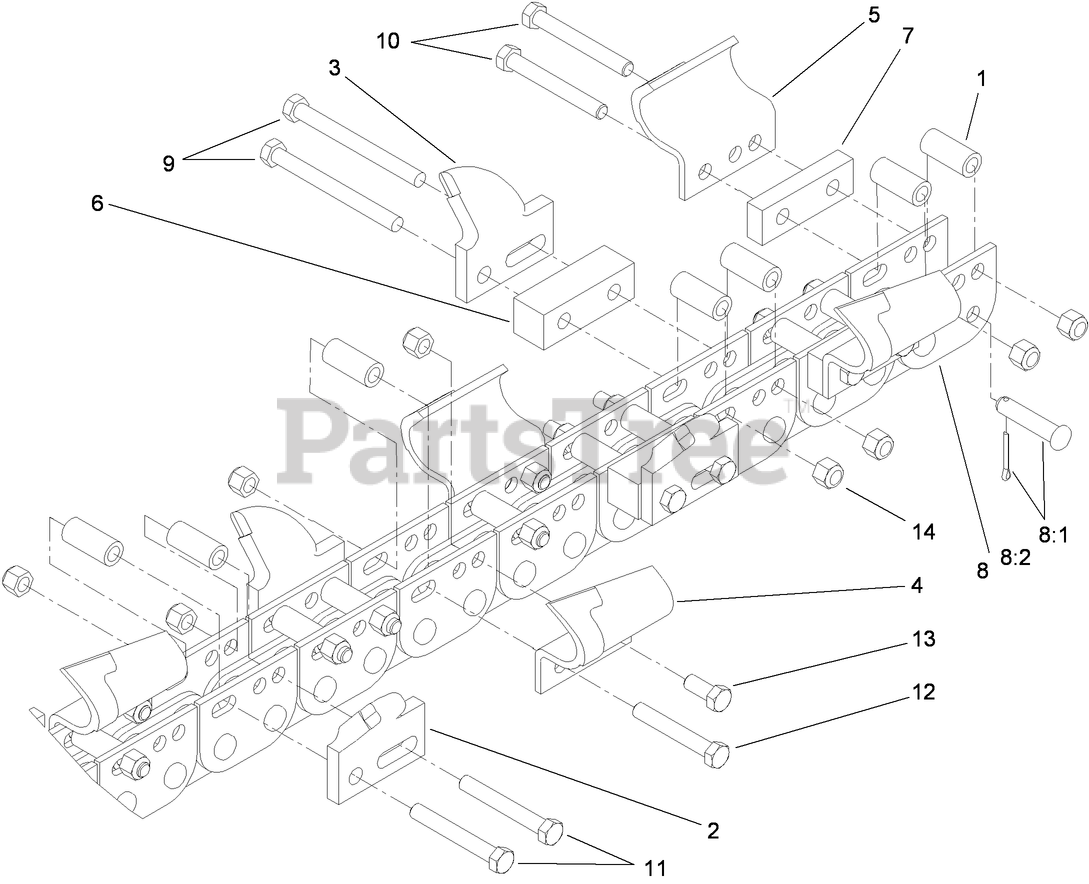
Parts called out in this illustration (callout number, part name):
1	SPACER-TUBE
2	TOOTH- ROCK, LH
3	TOOTH-ROCK, RH
4	TOOTH-SOIL, LH
5	TOOTH-SOIL, RH
6	SPACER-CUT, 6 INCH
7	SPACER-CUT, 5 INCH
8	CHAIN-BARE, 24 STATION
8:1	PIN-CONNECTING,
8:2	KIT-REPAIR, LINK
9	SCREW-HH
10	SCREW-HH
11	SCREW-HH
12	SCREW-HH
13	SCREW-HH
14	NUT-LOCK
